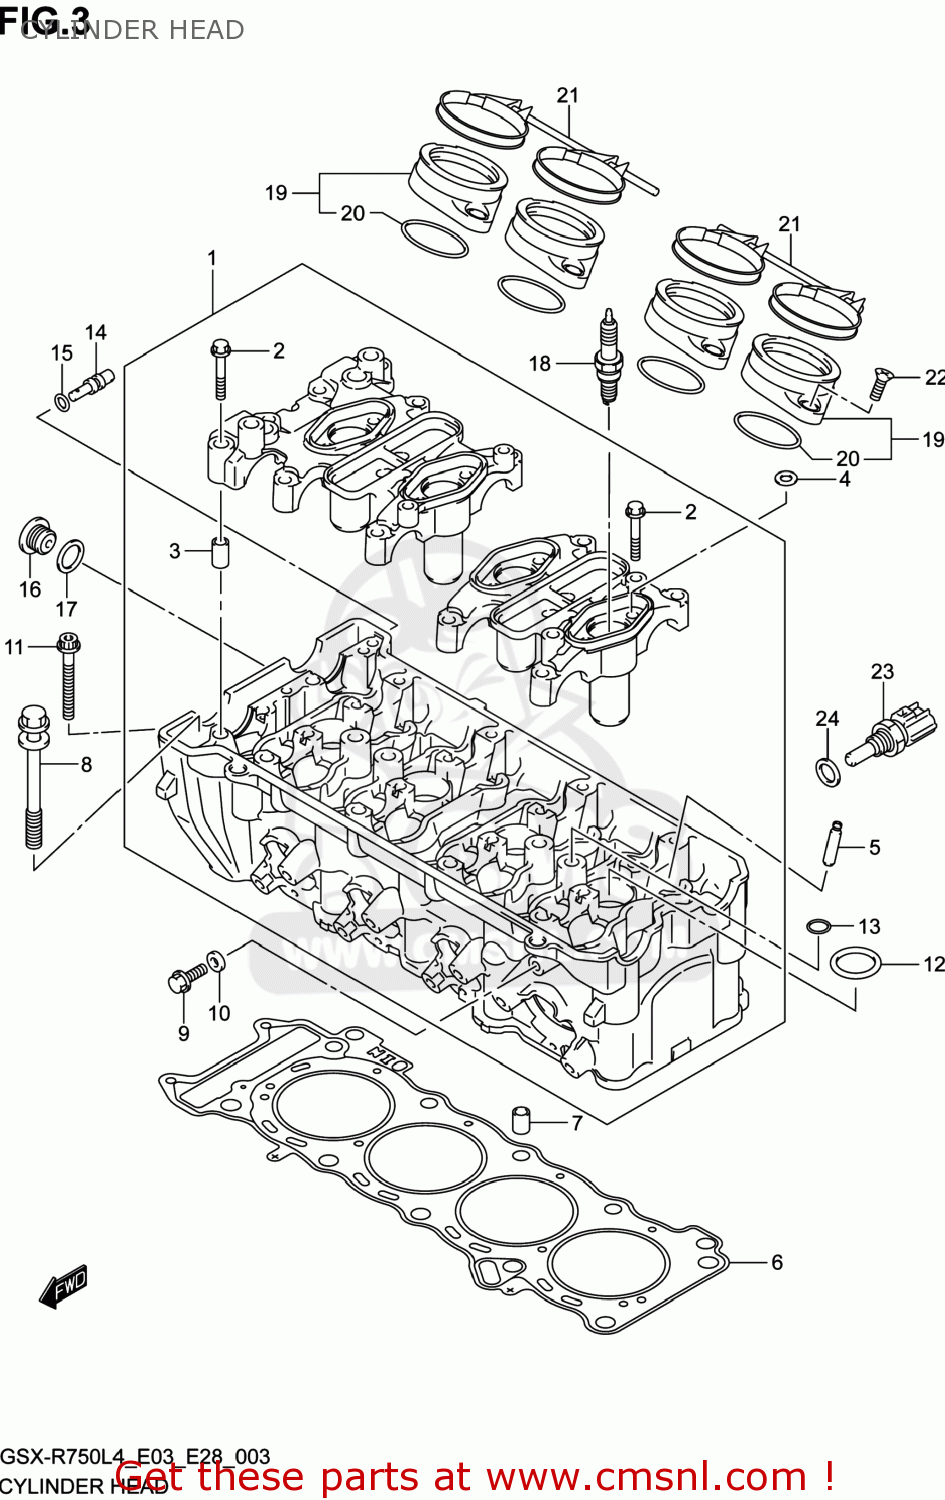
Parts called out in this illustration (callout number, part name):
1	HEAD ASSY,CYLINDER
2	BOLT(6X40)
3	PIN(6.2X8X16)
4	GASKET(6.2X13X1.2) (NAS)
5	GUIDE,VALVE(OS:0.3)
6	GASKET,CYLINDER HEAD (NAS)
7	PIN
8	BOLT,CYLINDER HEAD
9	BOLT(6X12)
10	GASKET(5.8X13X1.2) (NAS)
11	BOLT
12	O-RING
13	O RING(D:2.4,ID:10.8)
14	JET(8)
15	O RING(D:1.2,ID:4)
16	PLUG,16X8
17	GASKET(16X22X0.8) (NAS)
18	PLUG,SPARK(IU27D)
19	PIPE ASSY,INTAKE
20	O RING(D:2.4,ID:47X42)
21	CLAMP,INTAKE PIPE
22	BOLT(6X18.4)
23	SENSOR,TEMP
24	GASKET(12X17X1) (NAS)
